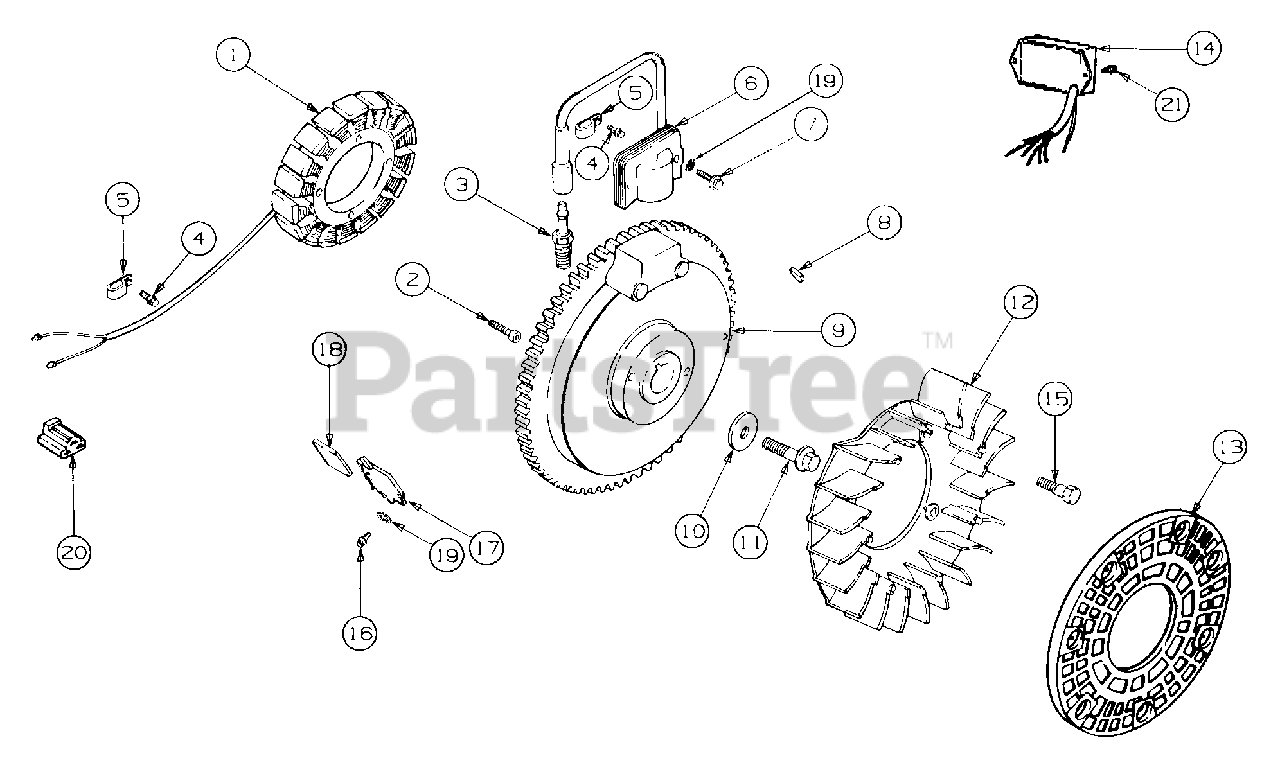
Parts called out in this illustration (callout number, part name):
1	Kit, Stator
2	Screw, Stator Mntg, 10-24 x 3/4
3	Spark Plug
4	Screw, Harness Clip, M5 x .8 x 10
5	Clip, Cable
6	Module, Ignition
7	Screw, Ign Module, M4 x .7 x 4.0
9	Flywheel Assembly
10	Washer, Flywheel
11	Screw, Flywheel, M10 x 1.5 x 46
12	Fan
13	Screen, Grass
14	Module, Digital Speed Advance
15	Bolt, Shoulder M6 x 1 x 16
16	Screw, Rectifier, M6 x 1 x 16
17	Rectifier-Regulator
18	Connector, Three Contact
19	Washer, Lock, 1/4
20	Connector, Three Contact
21	Screw, Pan Head, M4.2 x 13
